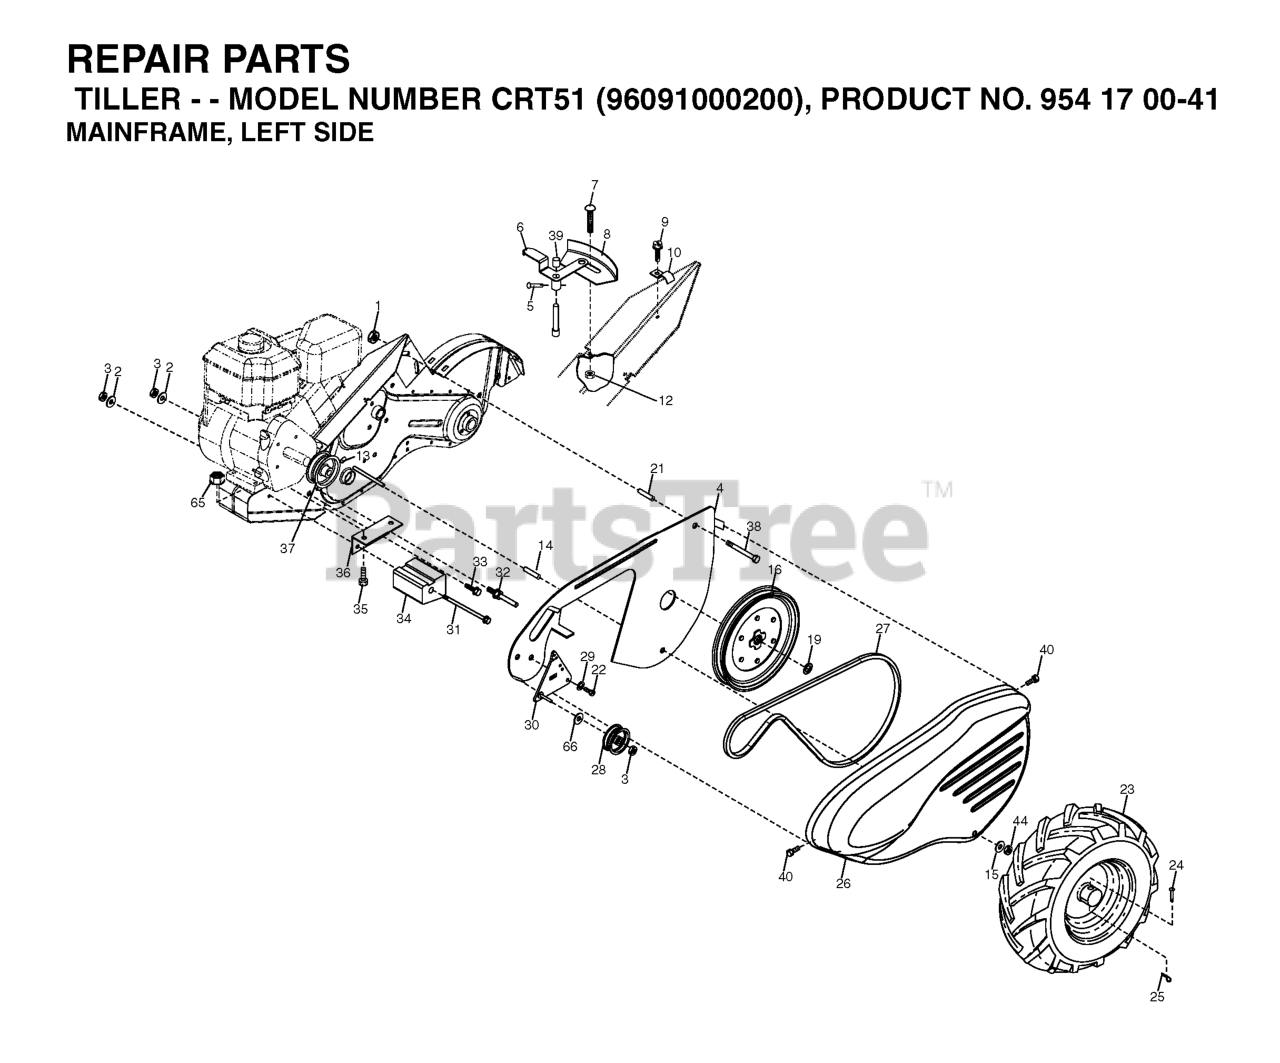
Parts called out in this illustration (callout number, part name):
1	NUT
2	WASHER, LOCK 3/8
3	NUT.HEX.3/8-16UNC
4	SHIELD
5	PIN.SPIROL.FLARED
6	LEVER ASM CRT
8	PANEL.INDICATOR.SHIFT.BLACK
9	TAPPING SCREW
10	CONDUIT.CLIP.PLATED
12	NUT
14	SPACER-SPLIT.327 X .42
15	WASHER
16	SHEAVE, TRANSMISSION
19	RETAINING RING LT
21	SPACER CRT
23	TIRE.16X4-8.CHEVRON.TILLER
24	RIVET,DRILLED
25	RETAINER M
26	RP BELT GUARD
27	V-BELT
28	PULLEY-IDLER TI
30	BRACKET.ASM.IDLER.BLACK
31	BOLT.FIN.HEX.3/8-16UNC
32	SHIFT ARM CRT
33	BOLT
34	COUNTERWEIGHT.LH.CRT
35	BOLT, HEX 5/16-18X1-3/4
36	BRACKET LH CRT
37	RP.ENGINE PULLEY
38	BOLT
39	CAP.PLUNGER.BLACK
40	SCREW.HEX.WSH.SLT.#10-24X.50
44	NUT.71038.31-18.HEX.NYLOCK
65	LOCKNUT-FLANGE 5/16-18
66	WASHER
